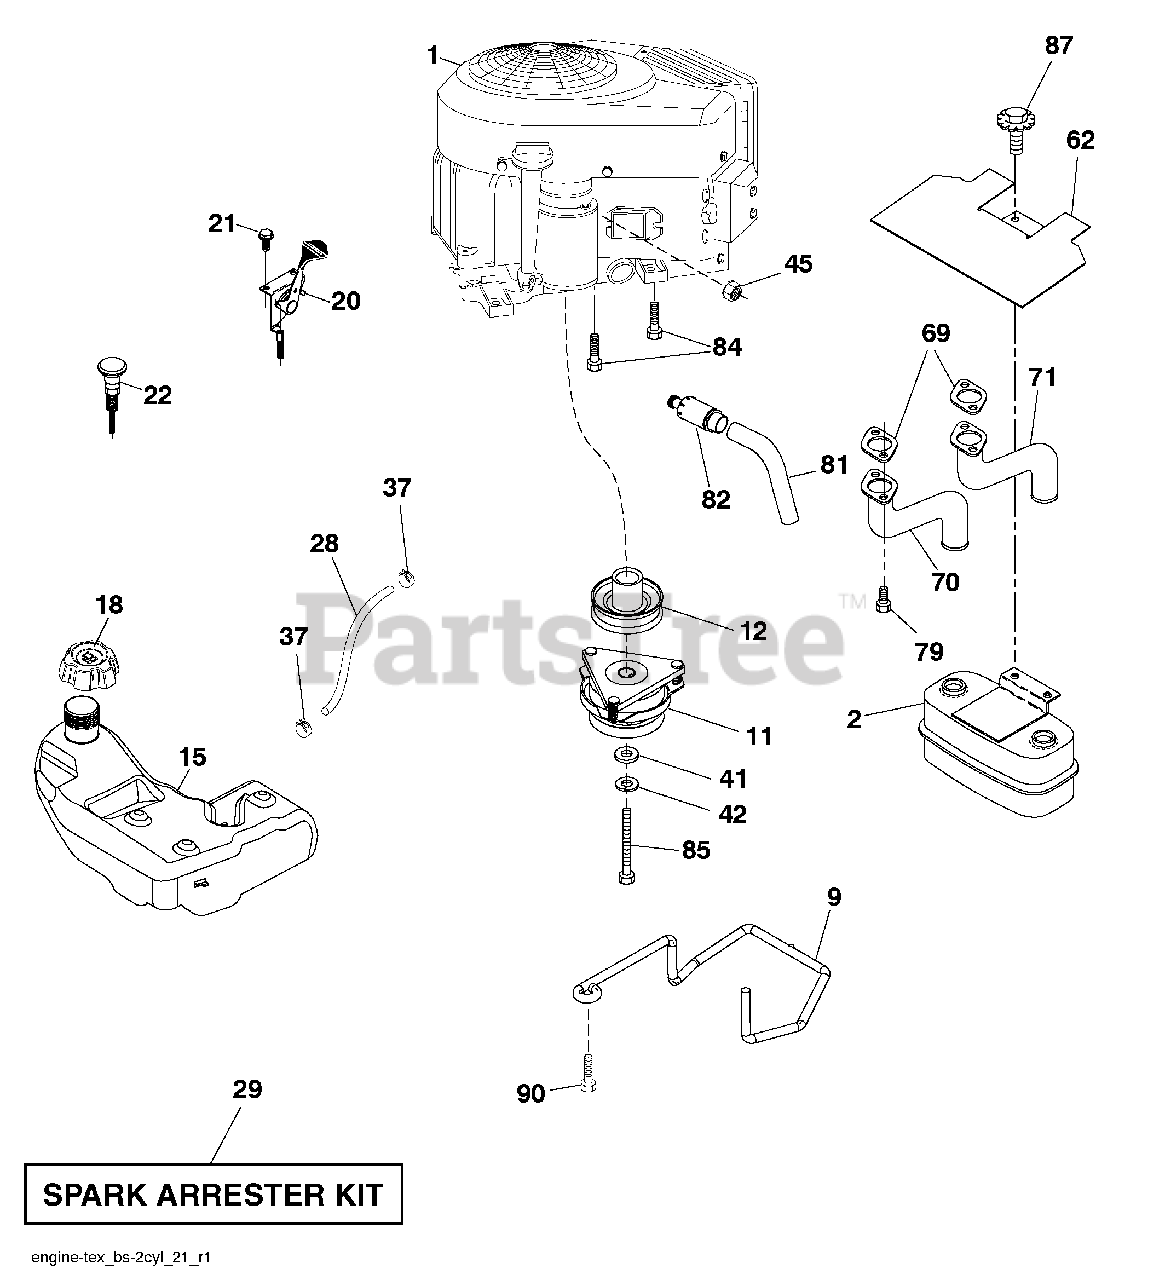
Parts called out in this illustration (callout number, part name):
9	Keeper Belt Engine
11	Clutch Electric
12	Pulley Engine
15	Tank Fuel
18	Cap Asm
20	Control Throttle
21	Screw #10 x 0.750 BOS Thread
22	Control Choke
28	Fuel Line
29	Spark Arrester Kit
37	Clamp Hose
41	Washer 1-1/2 OD x 15/32 ID x .250
42	Washer Lock 7/16
45	Nut Keps Hex 1/4-20 unc
62	Shield Heat Muffler
70	Tube Exhaust LH
71	Tube Exhaust RH
79	Screw Socket Head 5/16-18 x 1
81	Tube Drain Oil Easy
82	Valve Oil Drain
84	Screw 3/8-16 x 1-1/4
85	Bolt Hex 7/16-20 x 4 Gr. 5
87	Bolt 5/16-18 unc x 1 w/Sems
90	Screw 3/8-16 x 1
